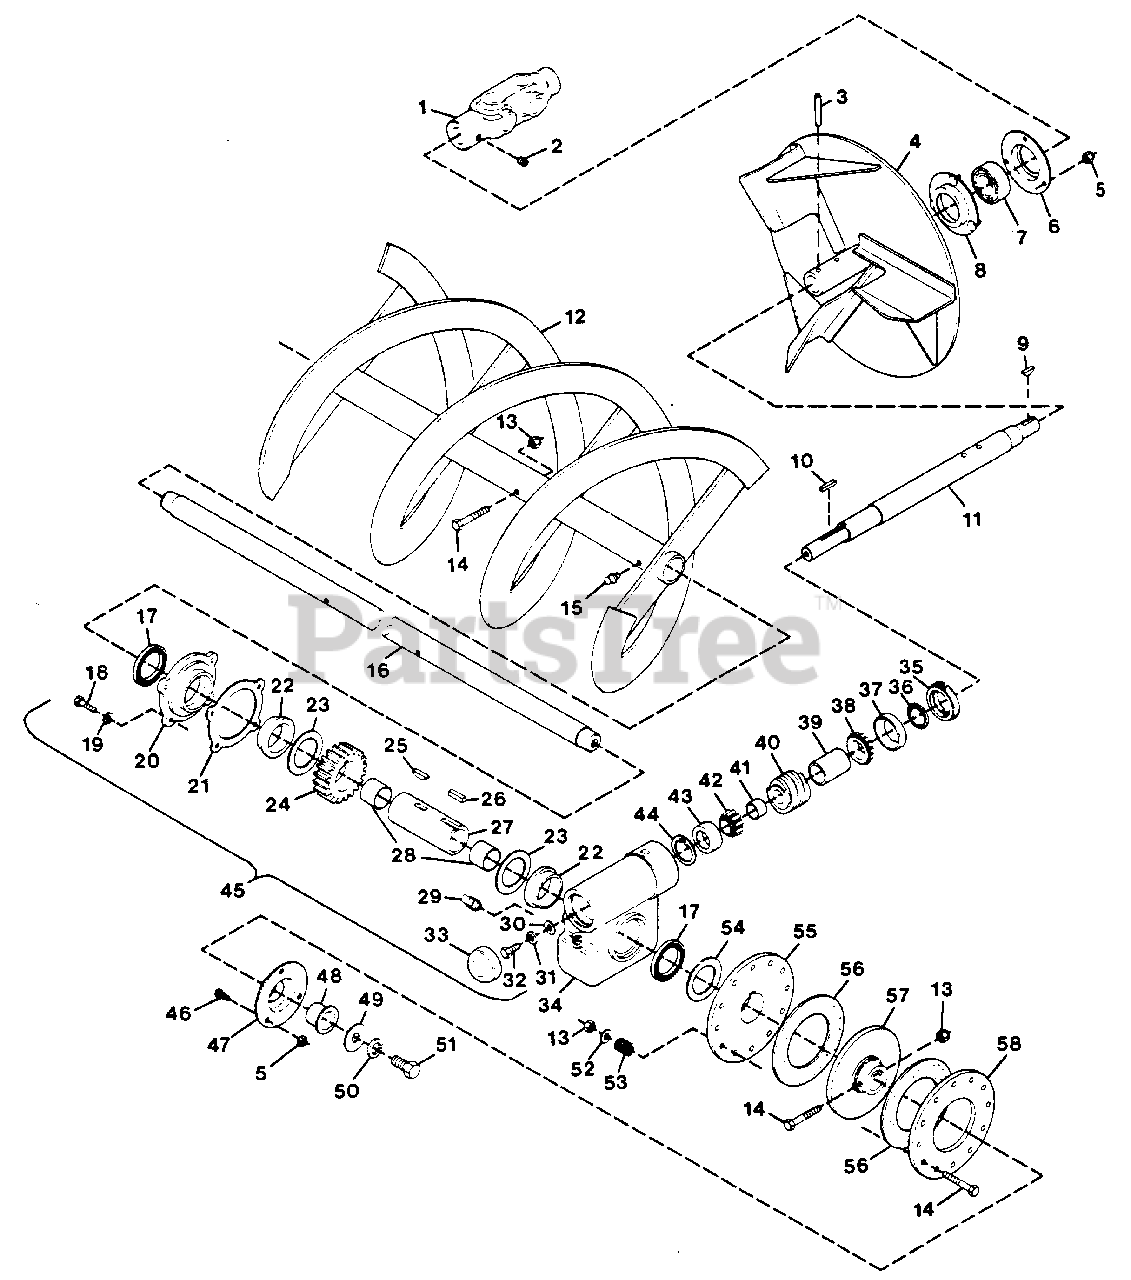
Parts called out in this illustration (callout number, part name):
1	Assembly, U-Joint
2	Screw, Set 3/8-16x.375
3	Pin, Roll 5/16x1.75
4	Fan, 16"
5	Nut, Lock 1/4-20
6	Bearing, Flange
7	Bearing, Ball
8	Bearing, Flange
9	Key, Woodruff 3/16x7/8 HRD #11
10	Key, Straight SAE 1035
11	Shaft, Worm 16"
12	Rake, Right 32"
12	Rake, Left 32"
13	Nut, Lock 5/16-18
14	Bolt, Hex 5/16-18x2.00
15	Fitting, Lube 1/4-28
16	Shaft, 32" Rake
17	Seal
18	Bolt, Hex 1/4-20x.875
19	Washer, Lock 1/4 Ext Th TYA
20	Cover, Gearcase
21	Gasket
22	Bushing, Flange 1.62x1.87x11
23	Washer, 1.625x2.50x.012
24	Gear, Worm
25	Key, Feather
26	Key, Straight
27	Shaft, Gearcase
28	Bushing, Sleeve
29	Plug, Pipe
30	Washer, Flat .344x.688x.065
31	Washer, Lock 5/16 SP
32	Bolt, Hex 5/16-18x.75
33	Cap, Dust
34	Gearcase
35	Plug, Adjustment
36	Seal
37	Cup, Bearing
38	Cone, Bearing
39	Spacer, Bearing
40	Worm
41	Spacer, Bearing
42	Cone, Bearing
43	Cup, Bearing
44	Ring, Snap Internal 1.781
45	Assembly, Gearcase
46	Bolt, Rib Neck 1/4-20x.5
47	Support, Bearing
48	Bushing, Flange 1x1.12x.625
49	Washer, Flat .515x1.441x.1
50	Washer, Lock 1/2 SP Heavy
51	Bolt, Hex 1/2-13x1
52	Washer, Flat
53	Spring, Compression
54	Washer
55	Driver
56	Disc, Friction
57	Plate, Driver
58	Plate, Pressure
